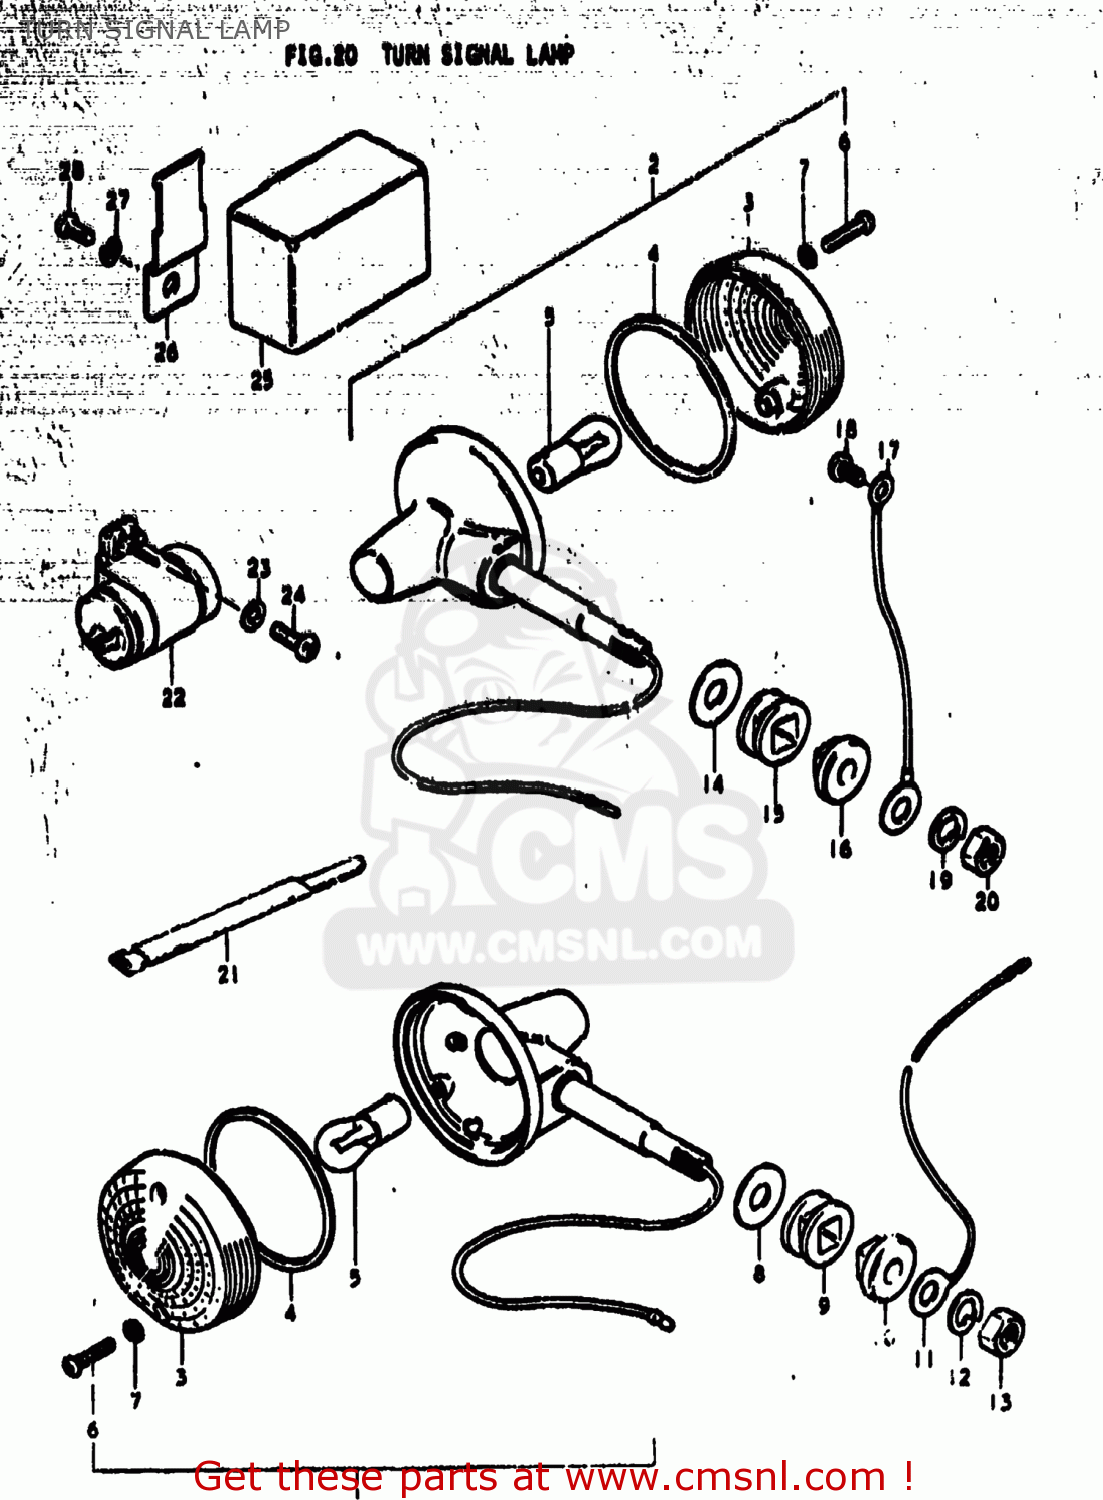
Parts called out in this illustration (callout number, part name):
1	LAMP ASSEMBLY,FRONT TURN SIGNAL
2	LAMP ASSEMBLY,REAR TURN SIGNAL
3	LENS
4	GASKET (NAS)
5	BULB(6V17W,STANLEY,A4513A)
6	SCREW
7	GASKET (NAS)
8	WASHER (10.5X30X2.3)
9	CUSHION
10	SPACER,RR TURNSIGNAL LAMP
11	LEAD WIRE,EARTH
12	LOCK WASHER
13	NUT
14	WASHER (10.5X30X2.3)
15	CUSHION
16	SPACER,RR TURNSIGNAL LAMP
17	LEAD WIRE
18	SCREW
19	LOCK WASHER
20	NUT
21	CLAMP
22	RELAY,TURN SIGNAL
23	WASHER
24	SCREW
25	RELAY,TURN SIGNAL
26	BRACKET,TURN SIGNAL RELAY
27	SCREW 6X12
28	LOCK WASHER
